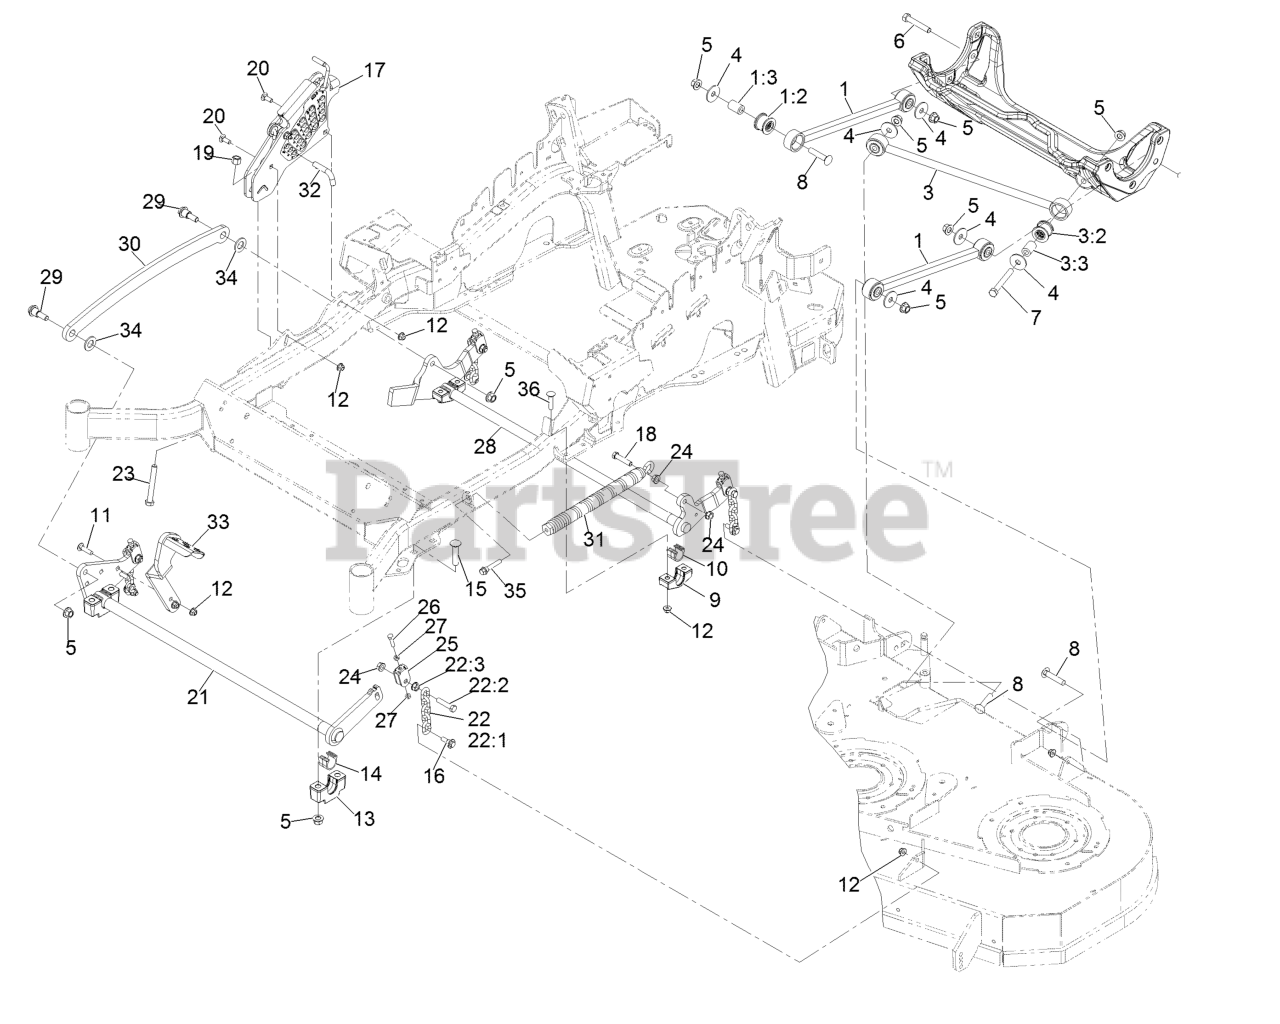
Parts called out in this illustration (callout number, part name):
1	Long Strut ASM
1:2	Bushing-Suspension, Rubber
3	Panhard Rod ASM
3:2	Bushing-Suspension, Rubber
5	Nut-Lock 1/2-13
6	Screw-HH 1/2-13 X 3
7	Screw-HH 1/2-13 X 4
8	Bolt-Carriage 1/2-13 X 2 1/2
9	Support-Cross Shaft, Bearing Rear
10	Bearing-Cross Shaft, Rear
11	Bolt-Carriage 3/8-16 X 1 1/2
12	Nut-Nyloc 3/8-16 Flg
13	Support-Cross Shaft, Bearing
14	Bearing-Cross Shaft, Front
15	Bolt-Carriage 1/2-13 X 2 1/2 Spl Neck
16	Screw-Hex Flange 3/8-16 X .80
17	HOC ASM
18	Screw-HH 7/16-14 X 2
19	Nut-Nyloc 1/2-13
20	Bolt-Carriage 3/8-16 X 1
21	Decklift-Front
22	Deck Lift Chain ASM
22:1	Chain-Lift, Deck
22:2	Screw-HH 7/16-14 X 2
22:3	Nut-Whizlock 7/16-14
23	Bolt-HH 1/2-13 X 4 Tap
24	Nut-Whizlock 7/16-14
25	Yoke-Adjust, Deck
26	Screw-HH 5/16-18 X 1 1/4
27	Nut-Jam 5/16-18
28	Lift-Deck, Rear
29	Screw-Shoulder HHF 1/2-13 X 1.12
30	Link-Lift, Deck
31	Spring-Extension
32	Pin-HOC
33	Lever-Foot
34	Washer-3/4 SAE
35	Screw-Shcs 3/8-16 X 2.212
36	Bolt-Carriage 3/8-16 X 2 1/4
